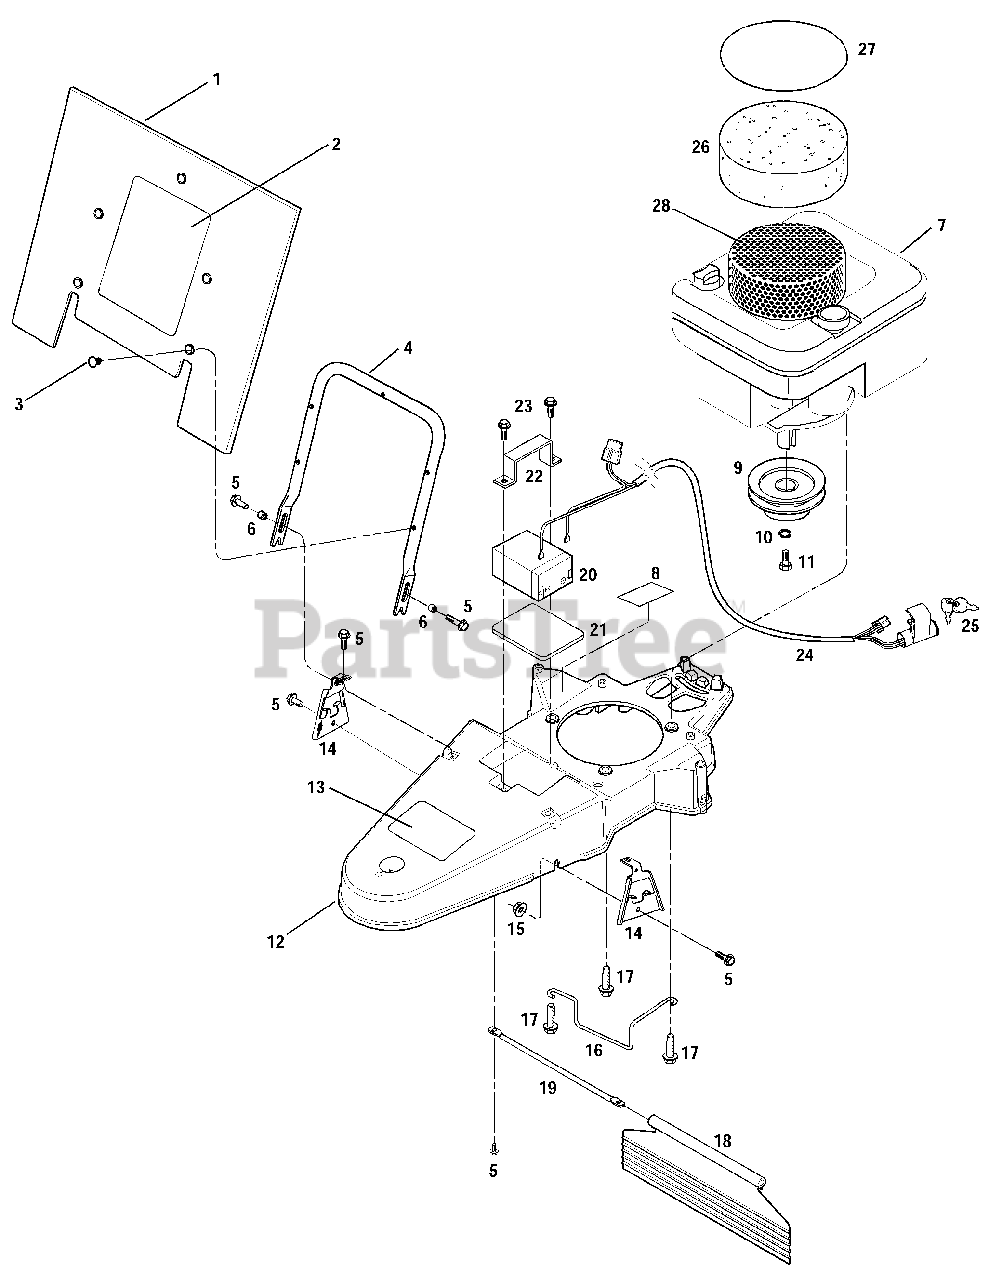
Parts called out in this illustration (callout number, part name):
1	Debris Guard
2	Decal-Logo
3	Push-in Fastener
4	Debris Guard Support
5	Hex Flange Screw, 1/4-20 x 3/4
6	Spacer
7	Engine
8	Decal-Hot Surface Warning
9	Engine Pulley
10	Spring Lock Washer
11	Hex Hd. Screw, 3/8-24 x 1, Grade 5
12	Deck
13	Decal-Warning
14	Hood Bracket
15	Flange Lock Nut, 1/4-20
16	Belt Guide
17	Hex Hd. Screw, 3/8-16 x 1-1/2
18	Deflector Flap
20	Battery
21	Battery Pad
22	Battery Clamp
23	Hex Flange Screw, 5/16-18 x 1
24	Wire Harness
25	Ignition Key
26	Foam Debris Guard
28	Engine Debris Guard (plastic)
